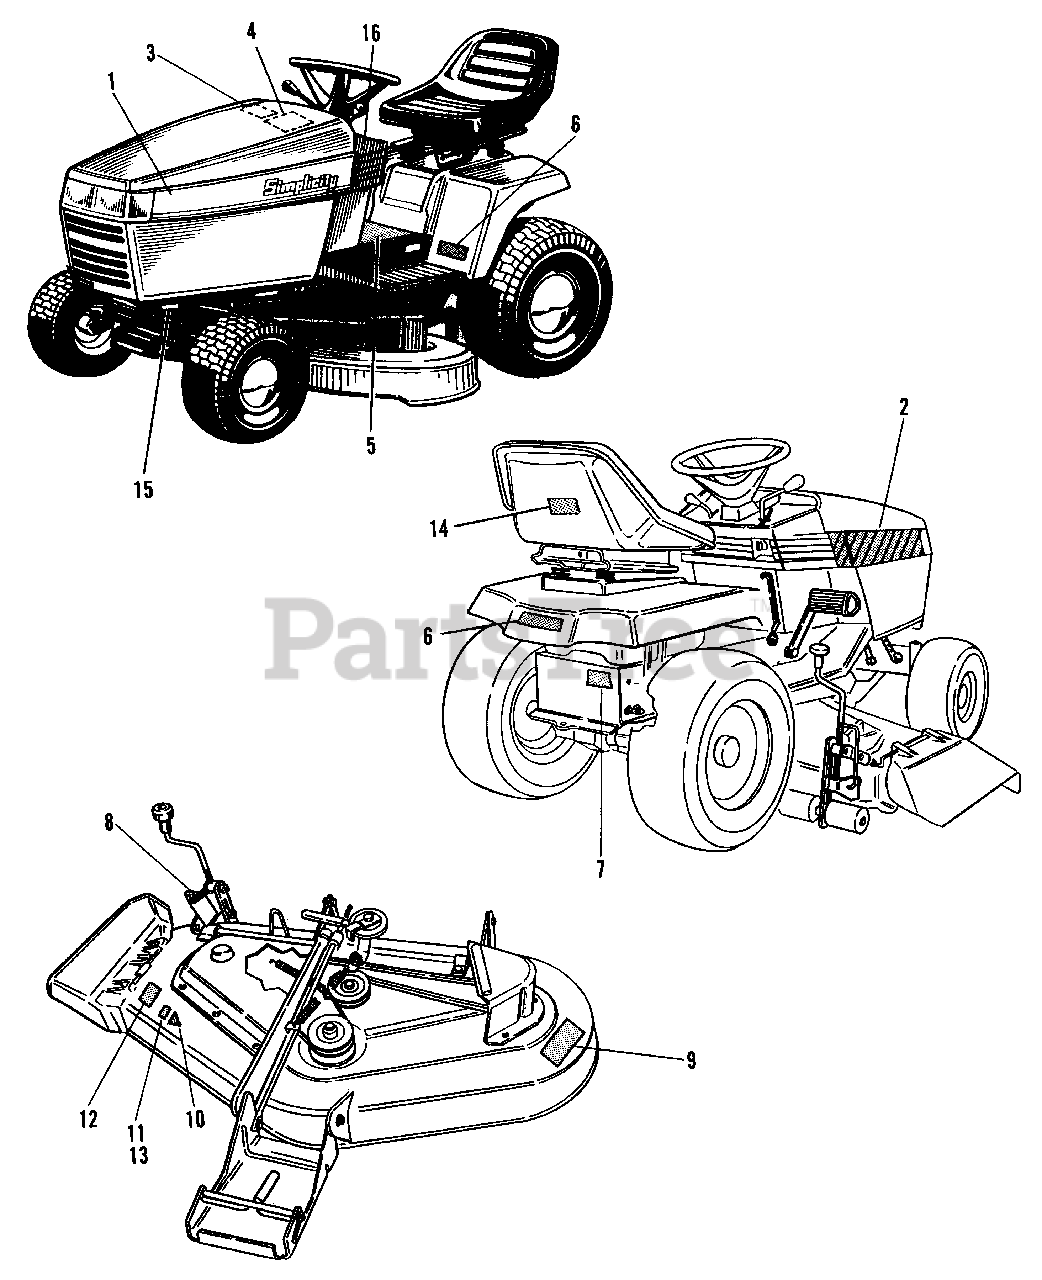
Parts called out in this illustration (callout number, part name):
1	DECAL, Hood, L.H., Broadmoor 16H
1	DECAL, Hood, L.H., Broadmoor 14H
1	DECAL, Hood, L.H., Broadmoor 12.5H
1	DECAL, Hood, L.H., Broadmoor 15G
2	DECAL, Hood, R.H., Broadmoor 16H
2	DECAL, Hood, R.H., Broadmoor 14H
2	DECAL, Hood, R.H., Broadmoor 12.5H
2	DECAL, Hood, R.H., Broadmoor 15G
3	DECAL, Paint
4	DECAL, Belt, Blade
5	DECAL, Operating Inst.
6	DECAL, Simplicity Logo
7	DECAL, Release Valve (Hydrostatic Units only)
8	DECAL, Mower Height
9	DECAL, Danger (Hand Under Deck)
10	DECAL, OPEI
11	DECAL, Cutting Width, 38"
12	DECAL, Danger (Chute in Place)
13	DECAL, Cutting Width, 44"
14	DECAL, USA Logo
15	I.D. PLATE
16	DECAL, Choke (Dash), 12.5 and 14 HP Kohler Only
16	DECAL, Battery
